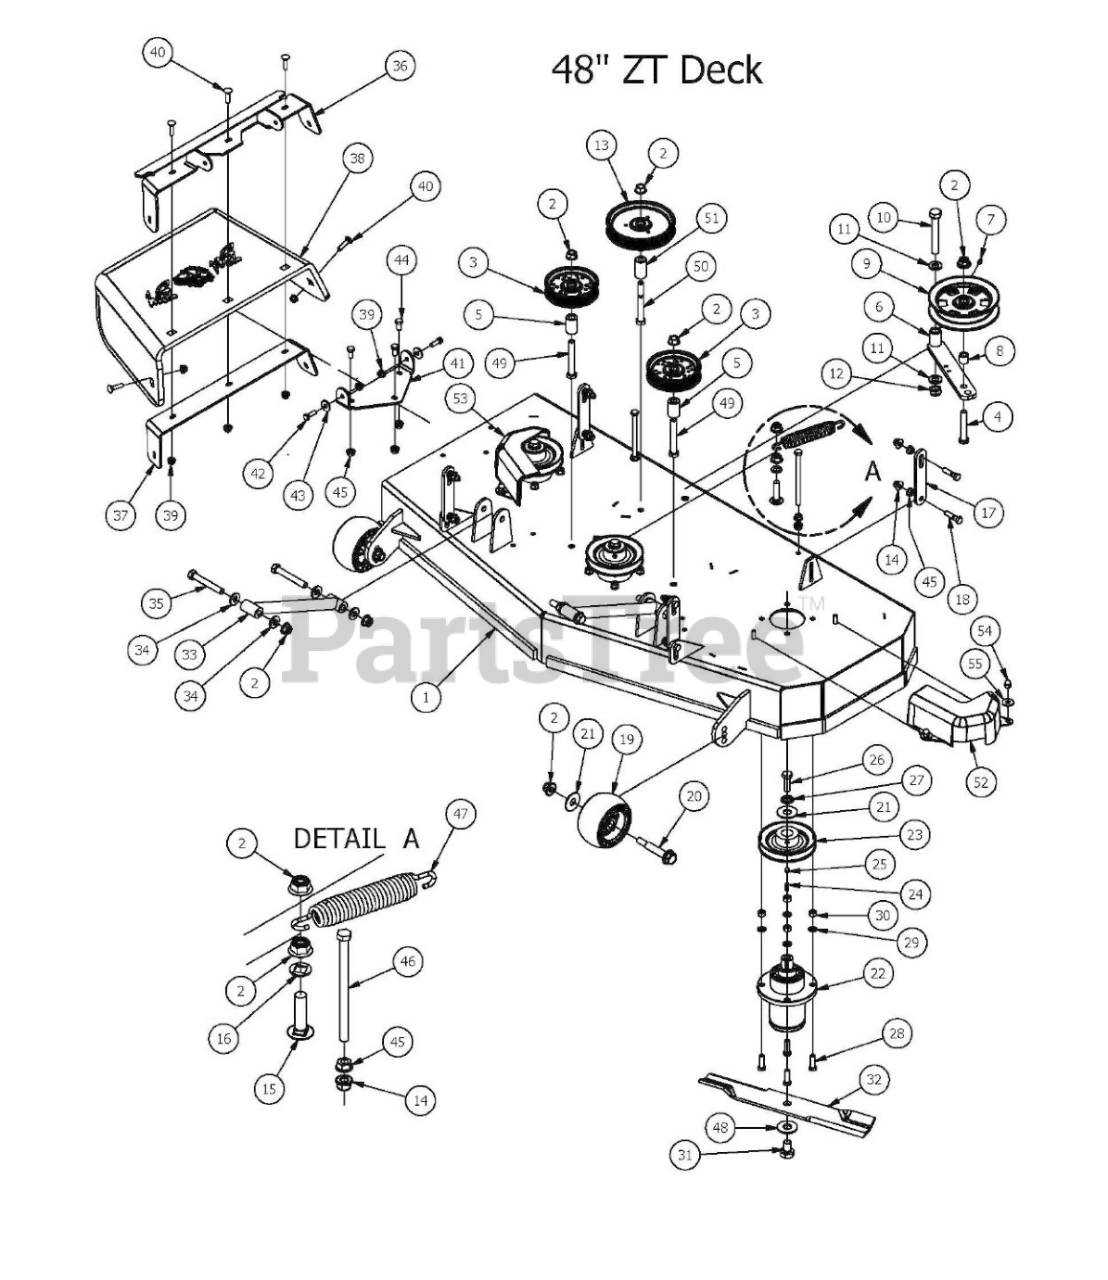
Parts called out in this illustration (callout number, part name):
1	2017 48" ZT Deck
2	1/2-13 Nylon Flange Nut
3	4 3/4 Idler Pulley - ABFI-76
4	1/2-13 x GR 5 Hex Bolt Zinc
5	Idler Pulley Standoff
6	Deck Idler
7	1/4" Press in Grease Fitting
8	Spacer 3/4 OD x 1/2 ID x 314 Length
9	5" Idler Pully
10	5/8" x 4" Hex Bolt
11	.630 ID Plastic Washer
12	5/8-11 Nylon Insert Jam Half Nut
13	5-3/4 Idler Pulley-Capitol Stampings
14	3/8 Nylock Flange Nut
15	1/2 x 2" Carriage Bolt
16	.517 Square Hole Round Washer
17	2017 MZ/ZT Deck Hanger
18	3/8" x 1 1/2" Hex Bolt
19	Deck Wheel
20	Deck Wheel Bolt
21	1/2" Belleville Washer
22	Spindle Assembly
23	5" Spindle Deck Pulley
24	1/4" x 1" Key
25	5/16 Set Screw
26	1/2"-20 x 1 1/2 - Grade 5 Fine Thread Bolt
27	1/2" Lock Washer Zinc
28	3/8" x 1 1/4" Hex Bolt
29	3/8" Lock Washer
30	3/8" Hex Nut
31	5/8" x 1 1/2" Grade 8 Hex Bolt (Fine)
32	16 1/4" Bad Boy Blade
33	MZ/ZT Deck Locator
34	.505 Nylon Spacer
35	1/2-13 x 3 1/2 GR 5 Hex Bolt
36	Discharge Upper Chute Bracket
37	Discharge Lower Chute Bracket
38	Rubber Discharge Chute
39	5/16" Nylon Flange Nut
40	5/16" x 1 1/4" Carriage Bolt
41	Discharge Chute Hanger (Deck Mounted)
42	5/16" x 1" Bolt
43	.360 ID Plastic Washer
44	3/8" x 3/4" Hex Bolt
45	3/8" Flange Nut
46	3/8-16 x 5 1/2 Hex Bolt
47	2015 Deck Idler Spring
48	5/8" Flat Washer
49	1/2 x 3 1/2 Flange Bolt Grade 8
50	1/2" x 4" Bolt (Grade 8)
51	1 3/4" Pulley Spacer
52	pulley cover non-chute side
53	pulley cover chute side
54	Acorn nut-pulley Cover
55	.360 ID Plastic Washer-Black
